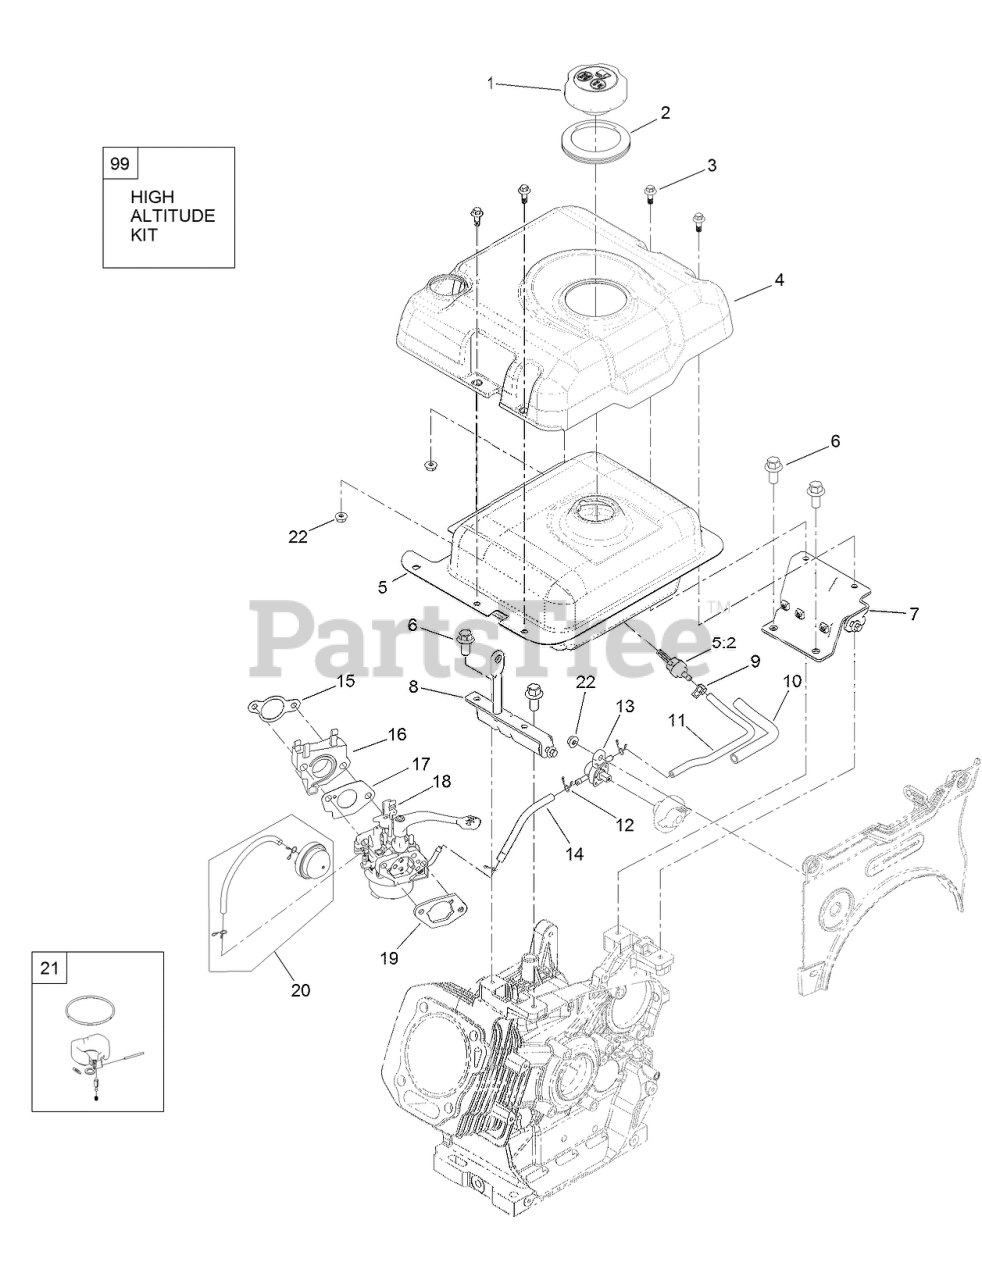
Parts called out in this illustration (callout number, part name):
1	CAP-FUEL
2	INSERT-COVER, TANK
3	SCREW-HHF
4	COVER-TANK, FUEL
5	FUEL TANK AND FILTER ASM
5:2	FILTER-FUEL
6	SCREW-HHF
7	BRACKET-TANK, RIGHT
8	BRACKET-TANK, LEFT
9	CLAMP-HOSE
10	SLEEVE-ABRASION
11	HOSE-FUEL
12	CLAMP-HOSE
13	VALVE-FUEL
14	HOSE-FUEL
15	GASKET-CARBURETOR
16	INSULATOR-CARBURETOR
17	GASKET-CARBURETOR
18	CARBURETOR ASM
19	GASKET-COATED, RUBBER
20	PRIMER KIT
21	INTERNAL CARB SERVICE KIT
22	NUT-FLANGE
99	HIGH ALTITUDE KIT
